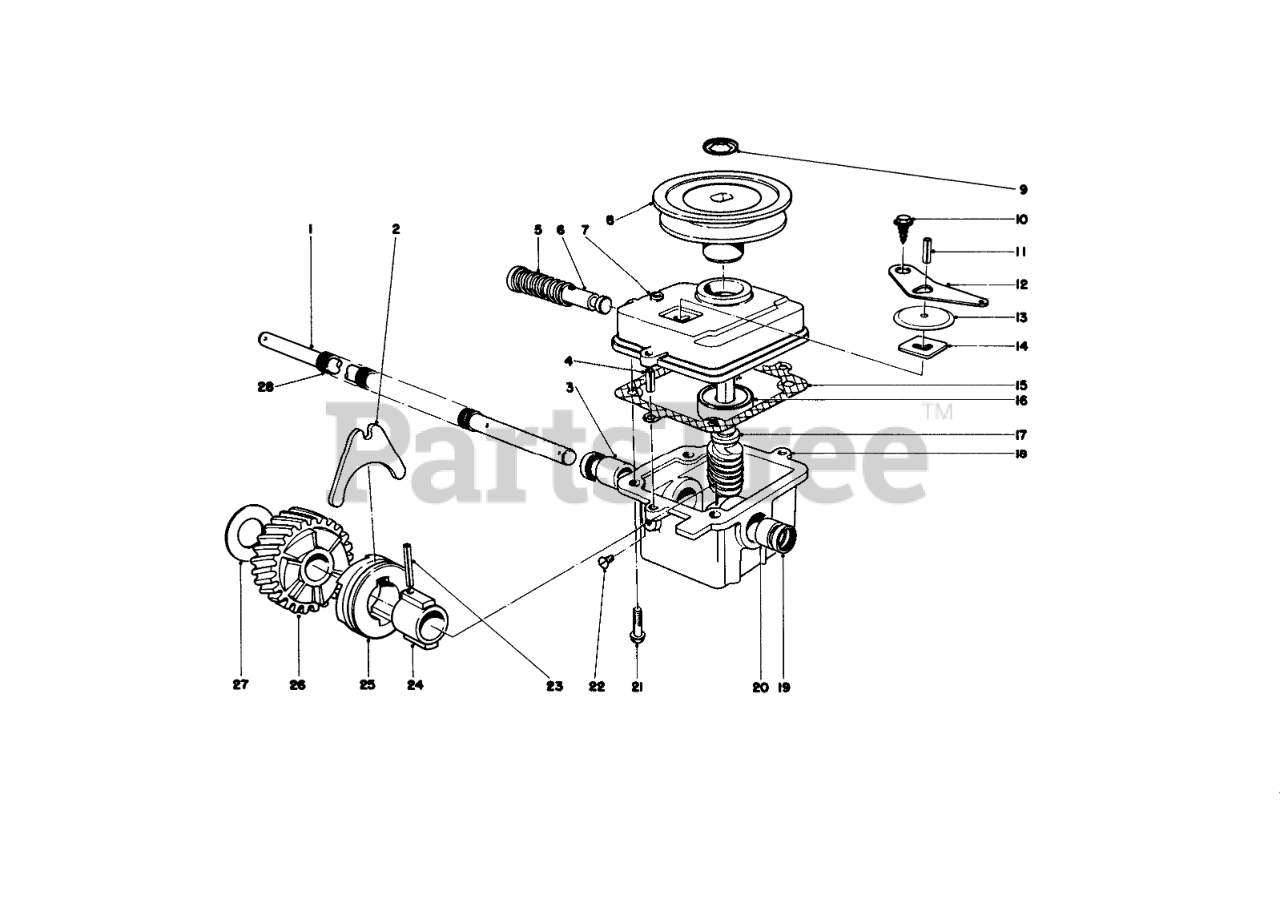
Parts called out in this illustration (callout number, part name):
1	Drive Shaft
2	SHIFTER FORK
3	Bushing
4	3/16 X 1/2 ROLL PIN
5	SPRING
6	Shift Rod
7	GEAR CASE COVER
8	PULLEY
9	PUSH-ON 93-3236
10	Screw
11	PIN-ROLL
12	SHIFTER ARM
13	TRANS DUST COVER
14	LATCH PLATE
15	GASKET
16	Bearing
17	WORM SHAFT
18	Gear Case (Incl. Ref. #3,19-20)
19	Seal
20	Bushing
21	Screw
22	NYLON SCREW
23	COIL PIN
24	SLEEVE
25	CLUTCH JAW
27	THRUST WASHER
28	DRIVE SHAFT COVER
